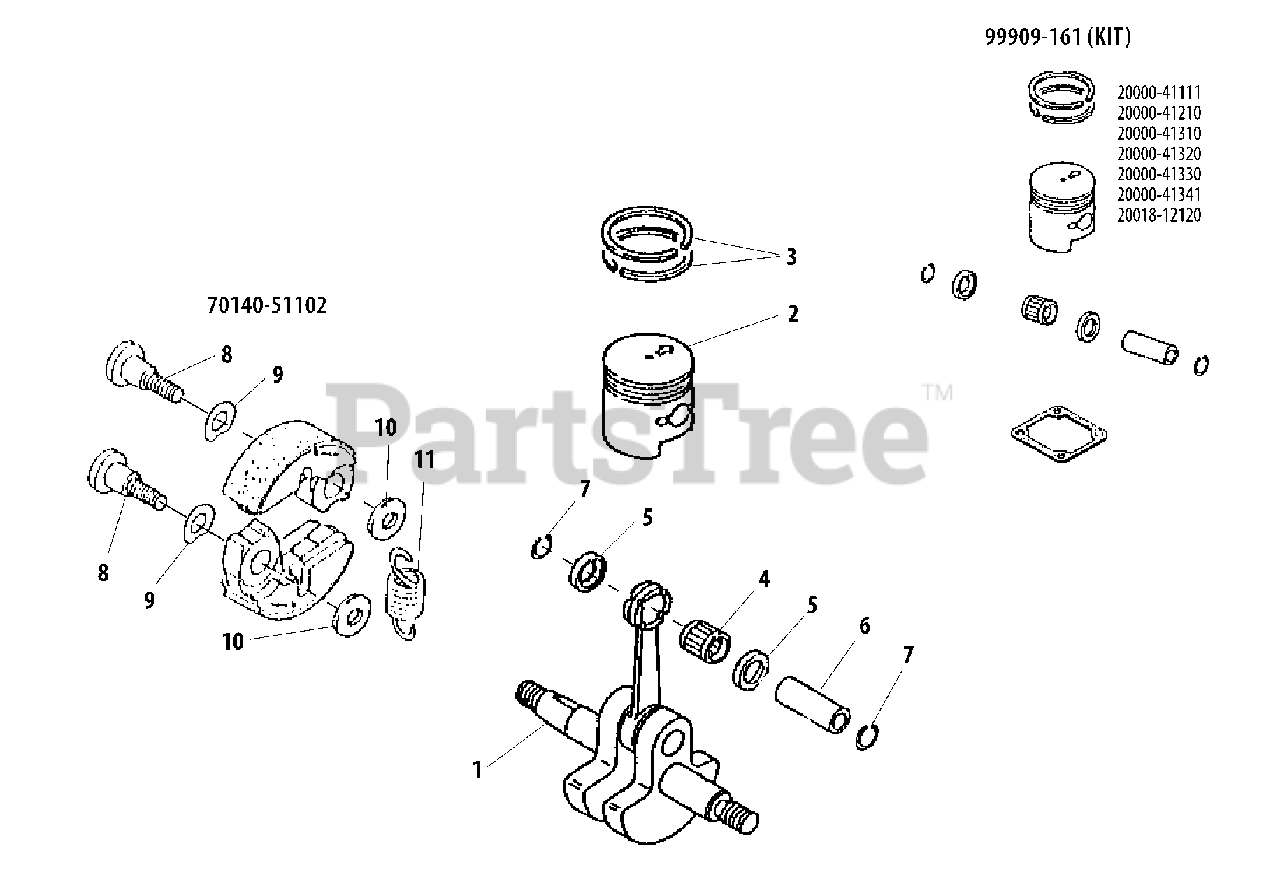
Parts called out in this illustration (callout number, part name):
1	CRANKSHAFT
2	PISTON
3	RING, PISTON
4	BEARING, NEEDLE
5	WASHER, THRUST - 9
6	PIN, PISTON
7	RING, SNAP
8	BOLT, CLUTCH
9	WASHER - SPRING
10	WASHER 6 MM
11	SPRING, CLUTCH
A	PISTON KIT
A	CLUTCH ASSY
